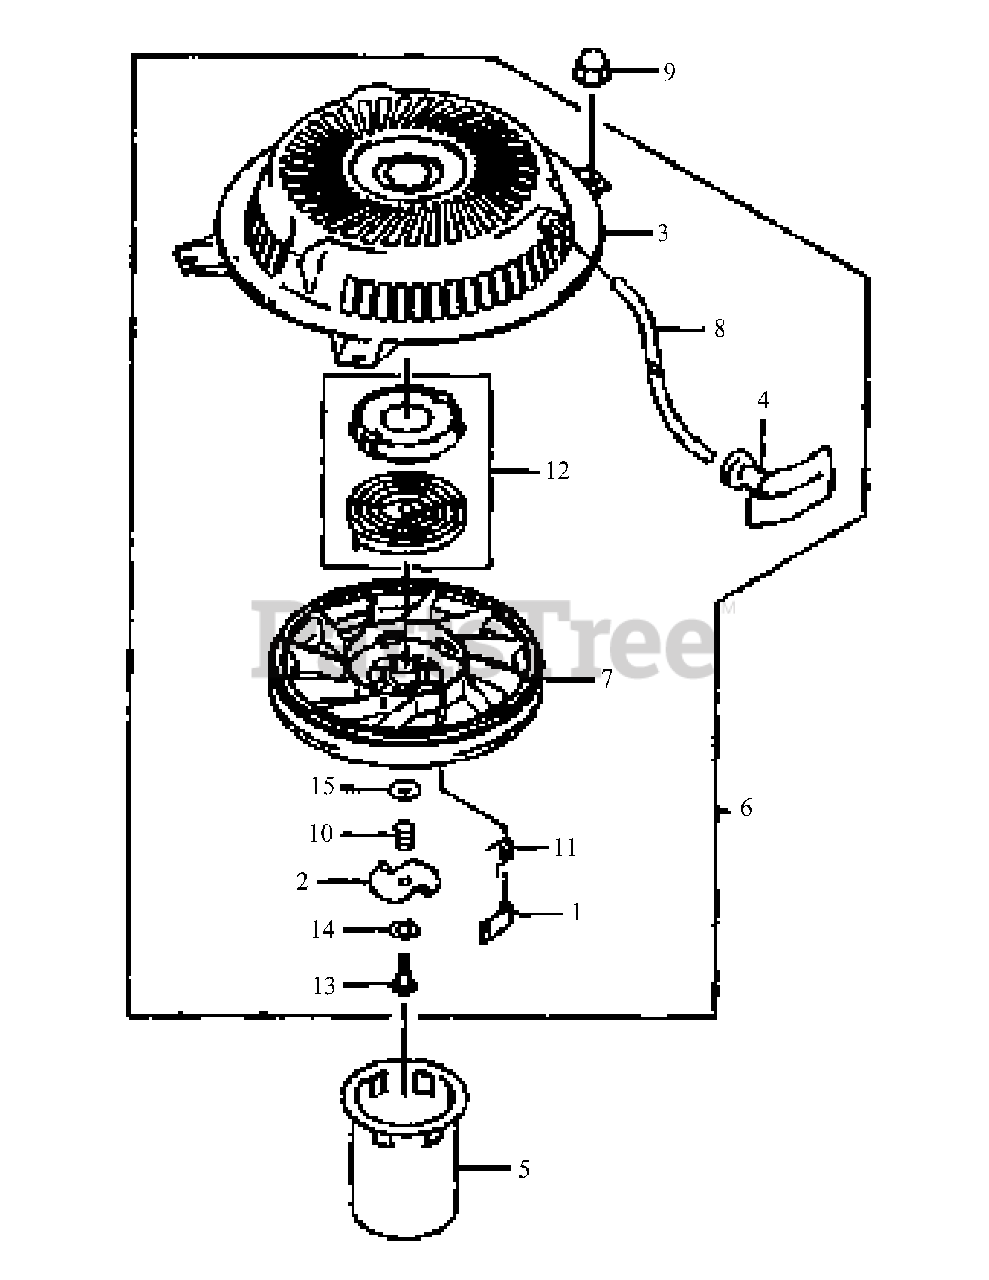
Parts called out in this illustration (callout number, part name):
1	Pawl, Recoil Starter
3	Case, Recoil Starter
4	Grip, Recoil Starter
5	Pulley, Starting
6	Starter, Recoil
7	Reel, Recoil Starter
8	Rope
